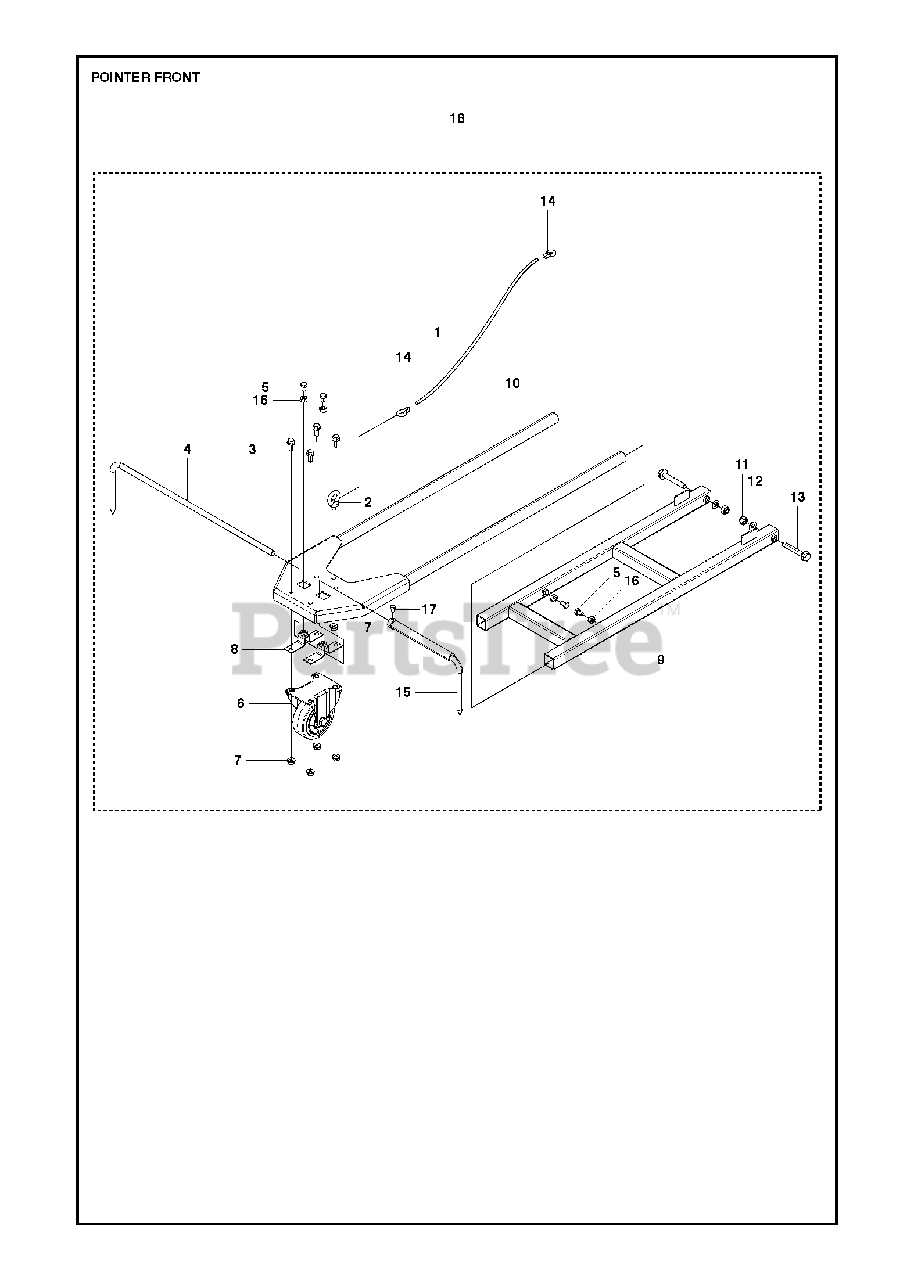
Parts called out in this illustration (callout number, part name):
7	HEXAGON NUT FLANGE
11	HEXAGON LOCKING NUT
12	WASHER
16	HEXAGON NUT
17	SCREW EHHM
